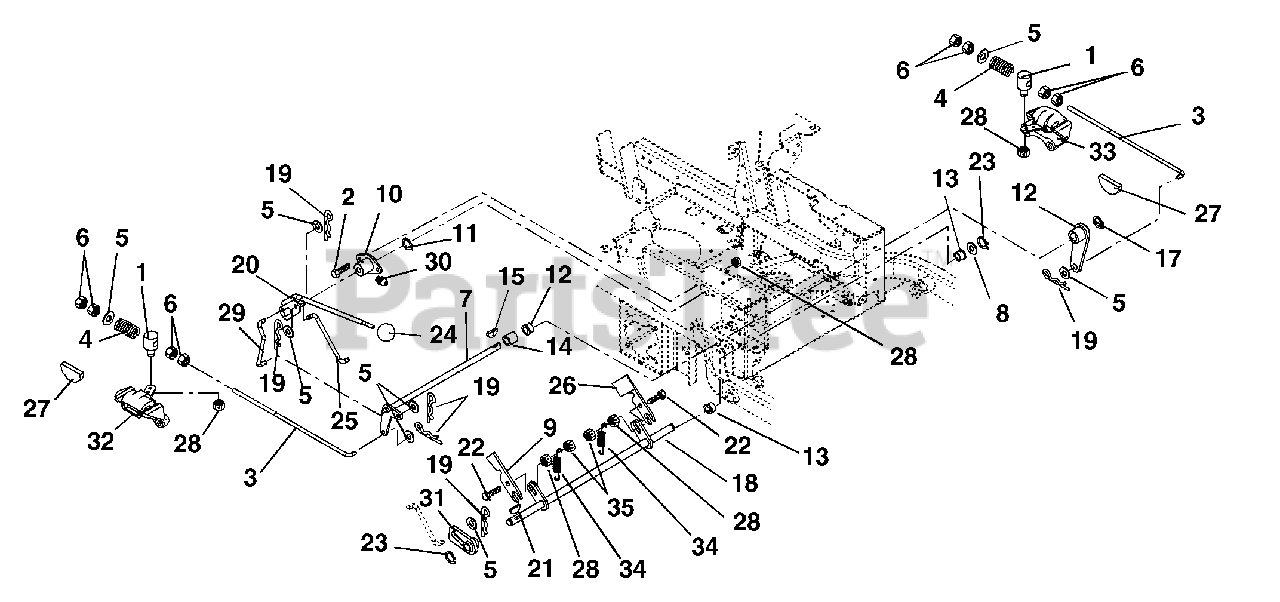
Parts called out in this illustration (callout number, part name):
1	Pivot, Brake Rod
2	Bolt, Hex .31-18 x .75 Grade 5
3	PTO Link Rod
4	Spring, Compression .143 x .710 x 2.00
5	Washer, Flat Steel .406 x .812 x .065
6	Nut, Hex .38-16
7	Weldment, Brake Cross Shaft
8	Washer, Flat Steel .505 x 1.00 x .062
9	Slide, Interlocking Brake
10	Bushing, Flange
11	Ring, Retaining External .625 x .05
12	Bushing, Flange Nylon .762 x 1.00 x .58 x 1.48
13	Bushing, Flange .50 x .75 x .75 x 1.00
14	Bushing, Sleeve .75 X 1.00 X .75
15	Key, Woodruff .19 x .75 Hard #9
16	Weldment, Brake Arm,
17	Ring, Retaining External .689 x .077
18	Weldment, Mechanical Brake
19	Pin, Hair
20	Weldment, Brake Actuating
21	Key, Woodruff .13 x .63
22	Bolt, Hex .31-18 x 1.25 Grade 5
23	Ring, Retaining External .50 x .05
24	Knob, Steering Lock
25	Linkage, Brake Actuating
26	Interlock, Safety Switch
27	Pad, Disk Brake
28	Nut, Locking Top Flange .31-18
29	Linkage, Brake Actuating
30	Fitting, Lube .25-28 x .256
31	Weldment, Parking Brake Hub
32	Brake, Right Hand Caliper
33	Brake, Left Hand Caliper
34	Spring, Tension .061 x .50 x 3.0
35	Nut, Locking Center .31-18
